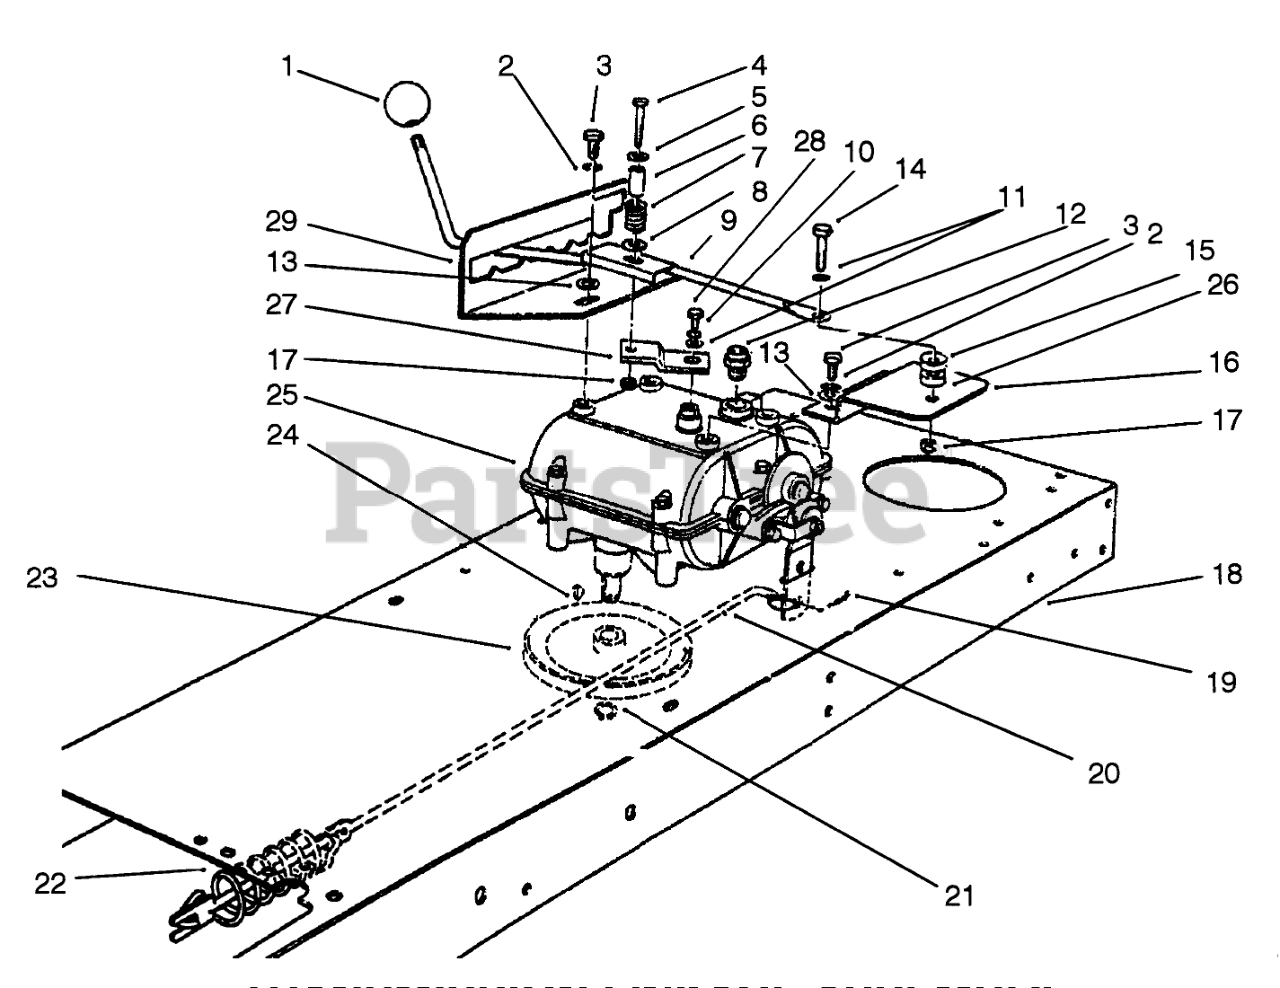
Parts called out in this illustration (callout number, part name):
2	WASHER-LOCK
3	SCREW-HWHTF
4	SCREW-HH
5	WASHER-FLAT
6	SPACER-SPLIT
7	SPRING-COMPRESSION
8	WASHER-FLAT
9	Lever-Shift
10	WASHER-LOCK
11	WASHER-FLAT
12	NEUTRAL SWITCH
13	WASHER-PLAIN
14	SCREW-HH
15	PUSH IN NUT
16	BRKT - SHIFTER MTG B
17	NUT-LOCK, NI
18	Frame-Main
19	Pin-Cotter
20	BRAKE ROD
21	RING-SNAP, EXTERNAL
22	SPRING-EXT
23	PULLEY
24	KEY-WOODRUFF
25	TRANSMISSION
26	SPACER-PIVOT
27	LEVER-SHIFT
28	SCREW-HH
29	Gate-Shift
